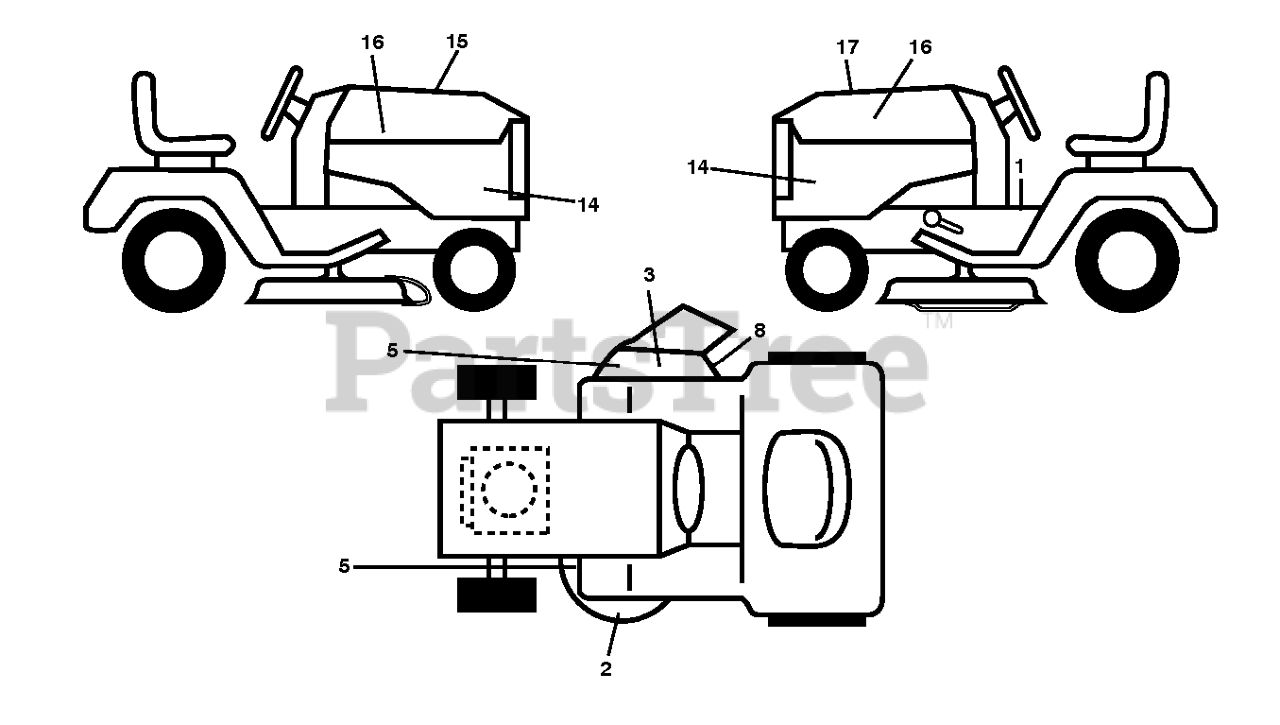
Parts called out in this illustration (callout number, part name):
1	DECAL.FENDER.WARNING.ENGLISH
2	DECAL DECK DECAL DECAL.48DECK.
3	DECAL.TRACT/ZTR.DECKWARN.HUSQ
5	DECAL.DECK.CLEARCUT.NOSTEP
8	DECAL.MOWER.SCH.48/54.PREM
14	DECAL TRACTOR SIDE PANEL DECAL
15	DECAL.WARNING.CUST.RESP.E85.
16	DECAL.BADGE.170MM.TEXTLOGO.
17	DECAL.RPL.KH.KT7.TGB.54F
